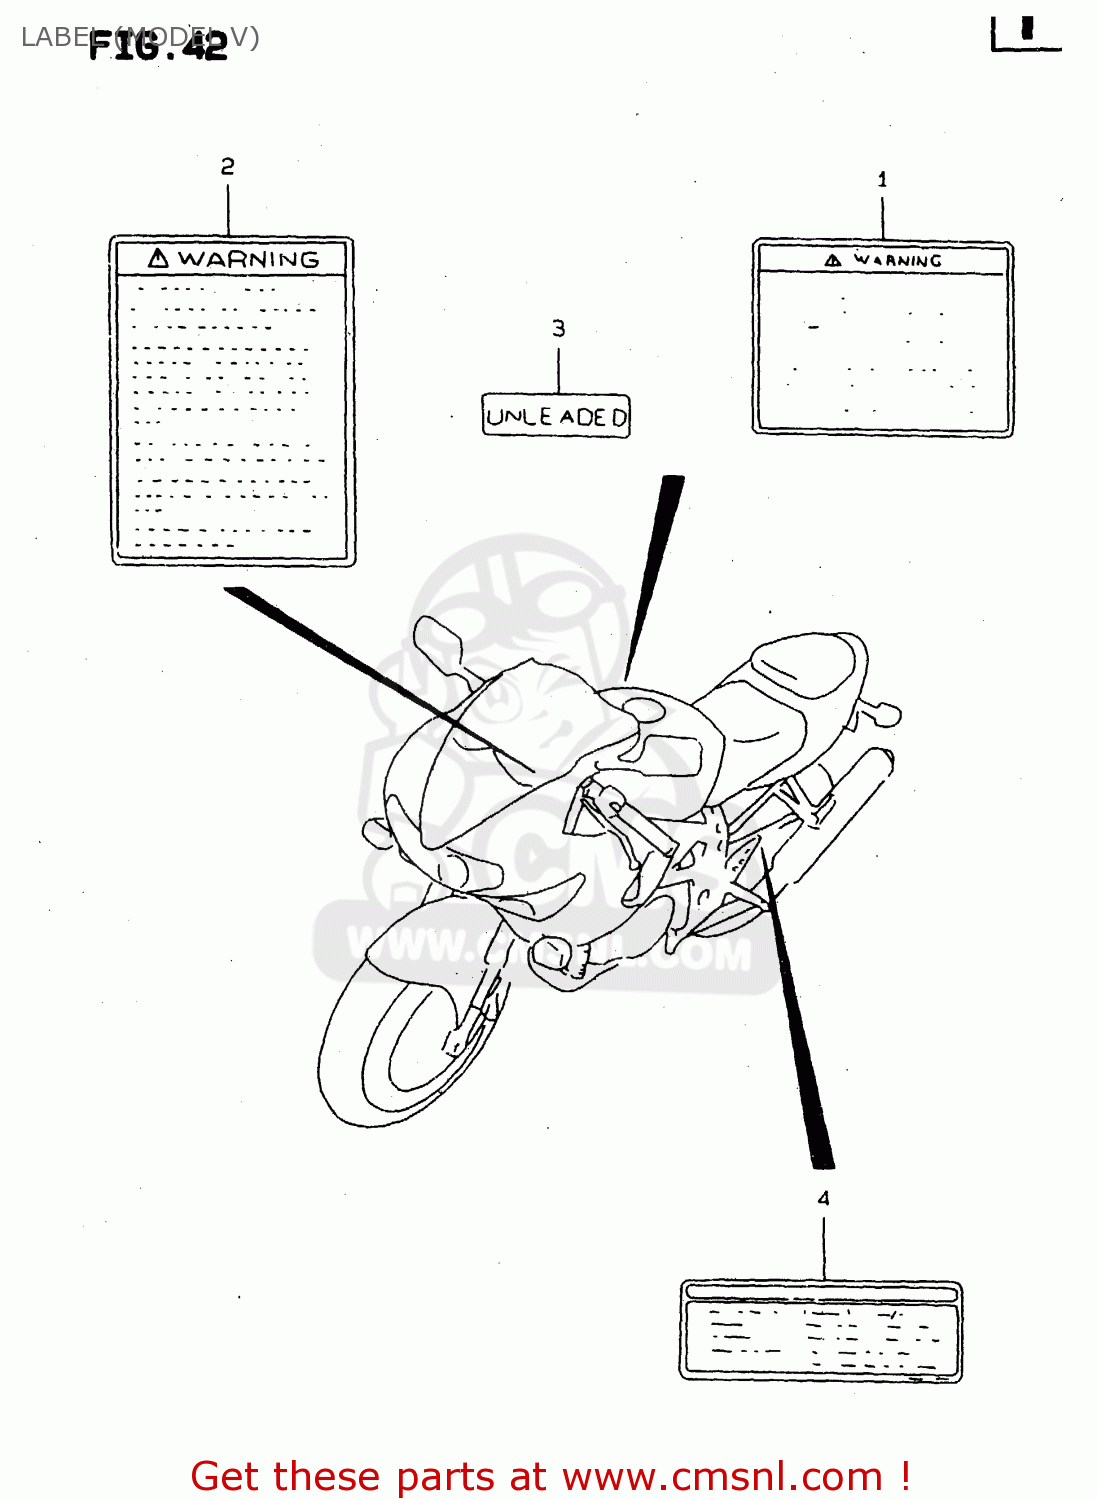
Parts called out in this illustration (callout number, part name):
1	LABEL,WARNING
2	LABEL (WARNING SCREEN)
3	LABEL,CAUTION
4	LABEL,TIRE AIR PRESSURE
5	O.M. TL1000S V
